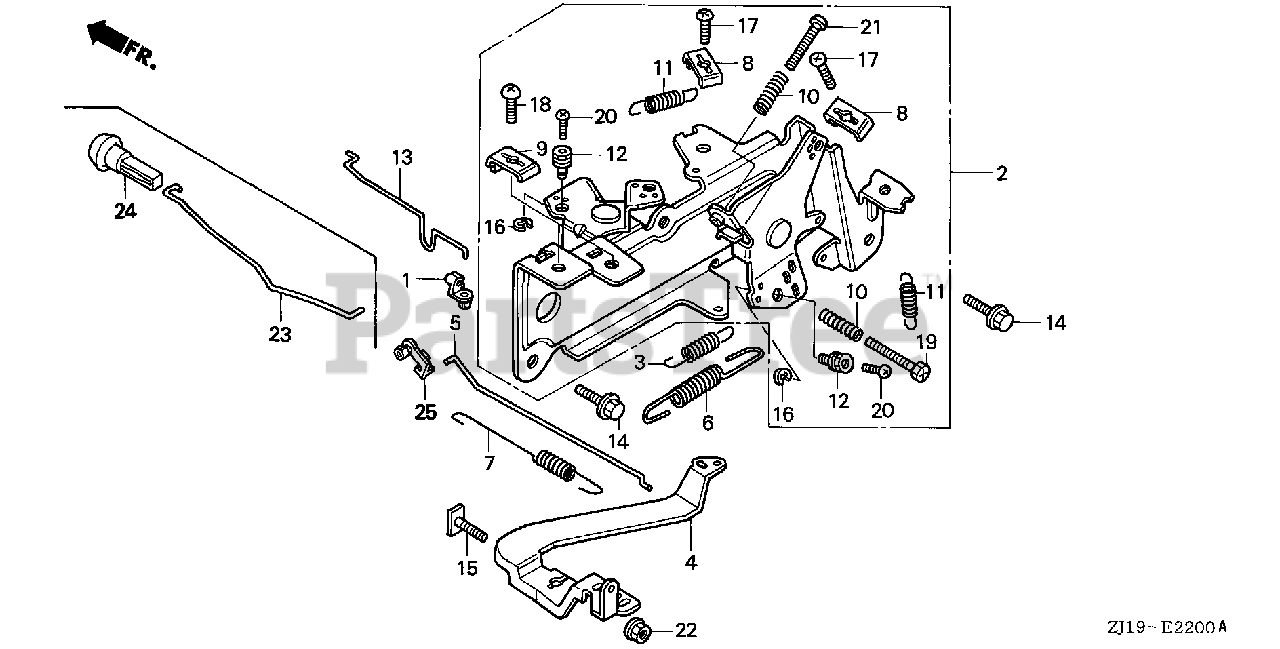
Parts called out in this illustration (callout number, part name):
1	JOINT, ROD
2	CONTROL ASSY.
3	SPRING, STARTER
4	ARM, GOVERNOR
5	ROD, GOVERNOR
6	SPRING, GOVERNOR
7	SPRING, THROTTLE RETURN
8	HOLDER, CABLE
10	SPRING, CONTROL ADJUSTING
11	SPRING, CABLE RETURN
12	HOLDER, CABLE
13	ROD, CHOKE CONTROL
14	BOLT, FLANGE (6X14)
15	BOLT, GOVERNOR ARM
16	CIRCLIP (5MM)
17	BOLT, SLOT (5X16)
19	BOLT, SLOT (5X25)
20	BOLT, RECESSED (4X6)
21	SCREW, PAN (5X25)
22	NUT, FLANGE (6MM)
23	ROD, CHOKE KNOB
24	KNOB, CHOKE
25	BUSH, LINKAGE
